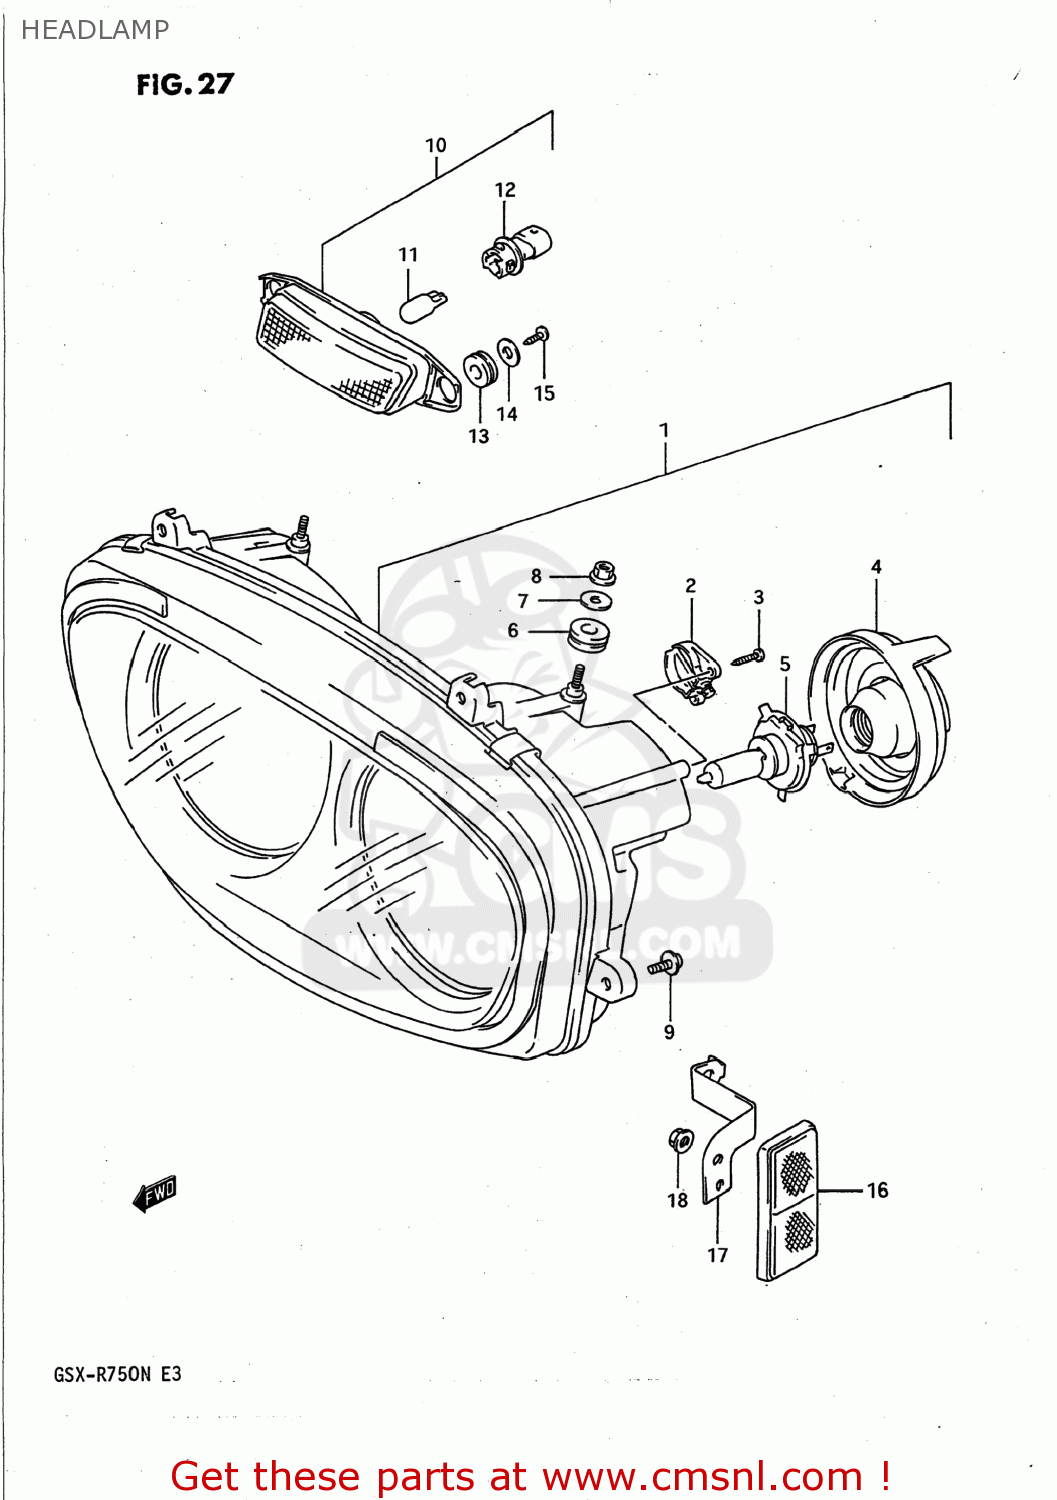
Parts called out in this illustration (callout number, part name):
1	HEADLAMP ASSEMBLY
2	GEAR UNIT ASSY,LWR
3	SCREW
4	COVER,SOCKET
5	BULB(12V60/55W,H4)
6	GROMMET
7	WASHER
8	NUT 6MM
9	SCREW
10	LAMP ASSY,FR POSITION
11	BULB(12V5W)
12	SOCKET ASSY
13	CUSHION
14	WASHER (4X16X1.2)
15	SCREW
16	REFLEX REFLECTOR,FR SIDE
17	BRACKET,FR SIDE RR,R
18	NUT
